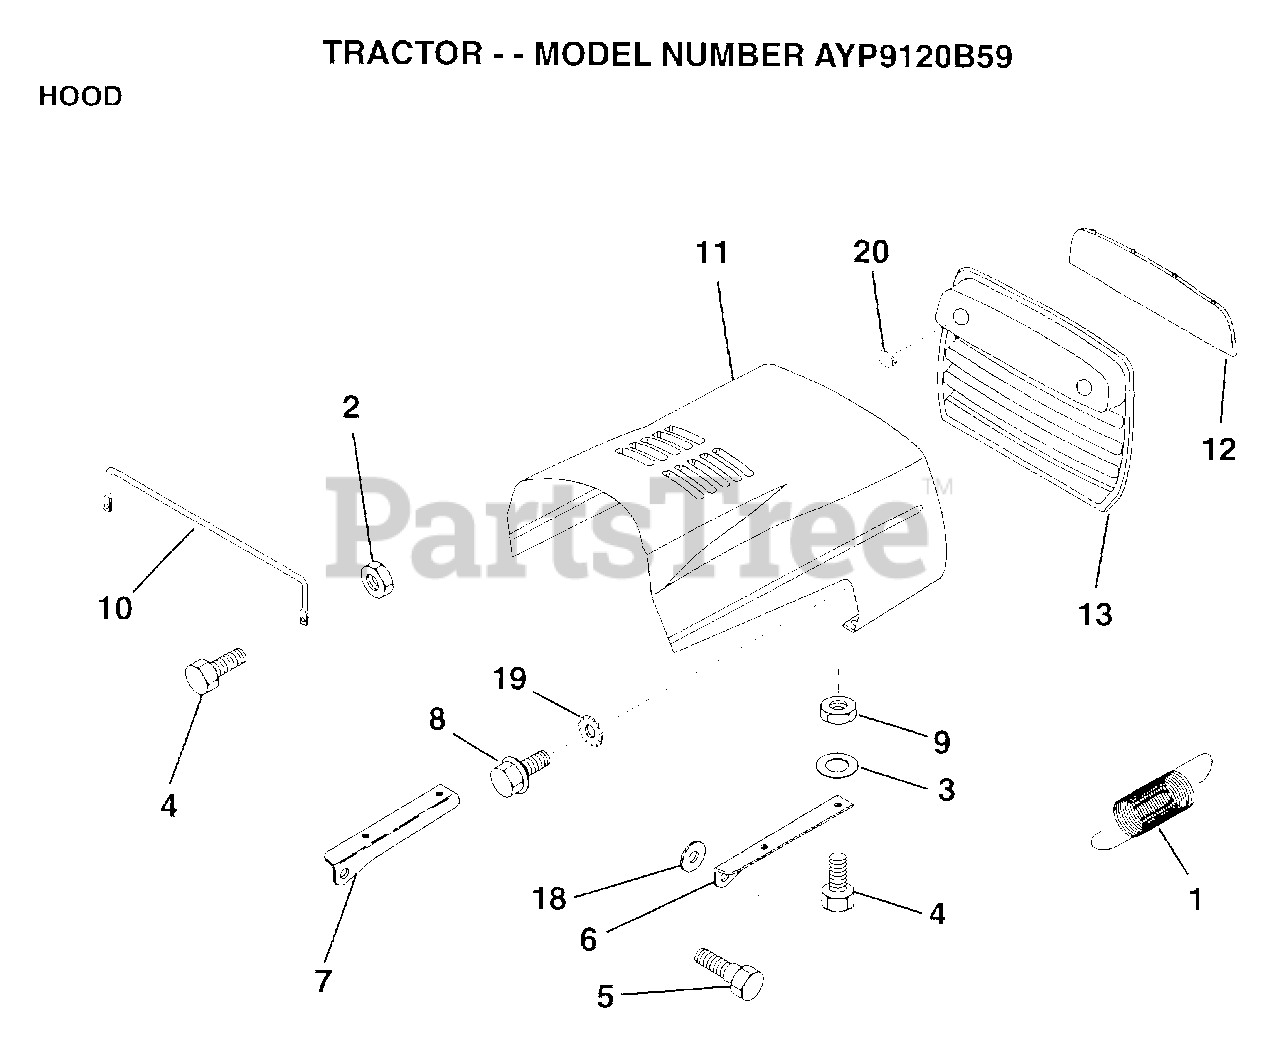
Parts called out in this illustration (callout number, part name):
1	EXT SPRING
2	NUT HXKEP 1/4X20
3	WASHER
5	BOLT.SHLD.5/16-18
6	BRKT HOOD RH
7	BRKT HOOD LH
9	NUT
10	"BRACE,HOOD"
11	HOOD
12	LENS
13	GRILL
18	WASHER
19	LOCKWASHER GT
